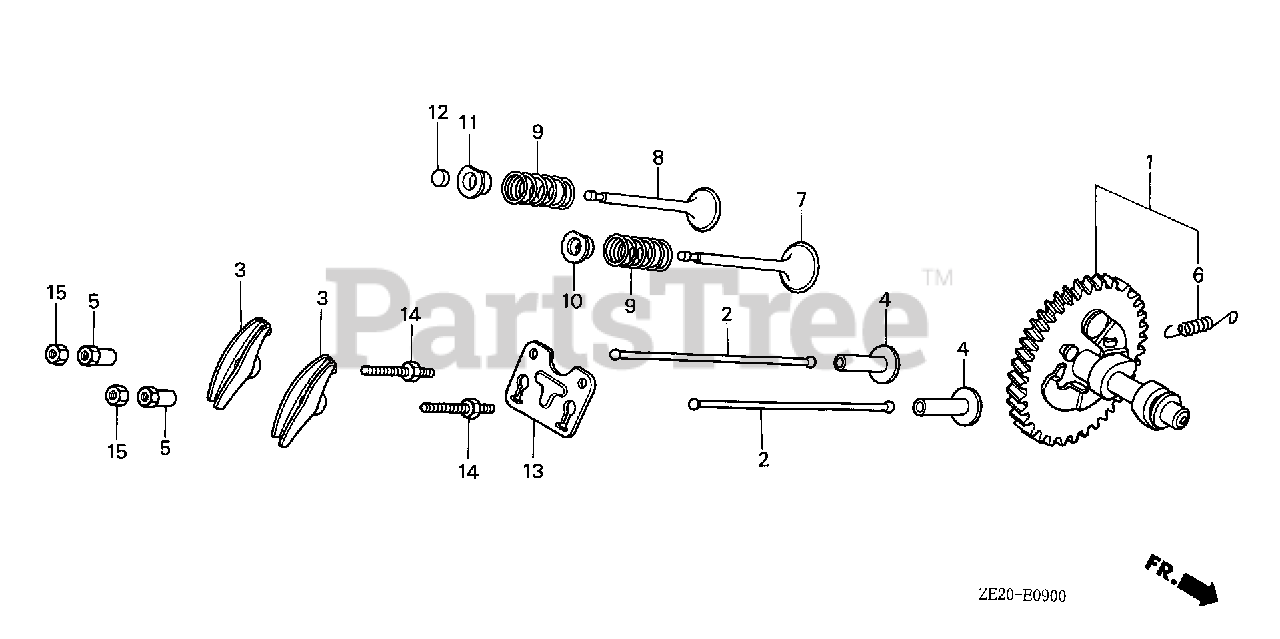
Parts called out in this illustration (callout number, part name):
1	CAMSHAFT ASSY. (NOT AVAILABLE)
3	ARM, VALVE ROCKER
4	LIFTER, VALVE
5	PIVOT, ROCKER ARM
6	SPRING, WEIGHT RETURN
7	VALVE, IN.
8	VALVE, EX.
9	SPRING, VALVE
10	RETAINER, IN. VALVE SPRING
11	RETAINER, EX. VALVE SPRING
12	ROTATOR, VALVE
13	GUIDE, PUSH ROD
14	BOLT, PIVOT (8MM)
15	NUT, PIVOT ADJUSTING
